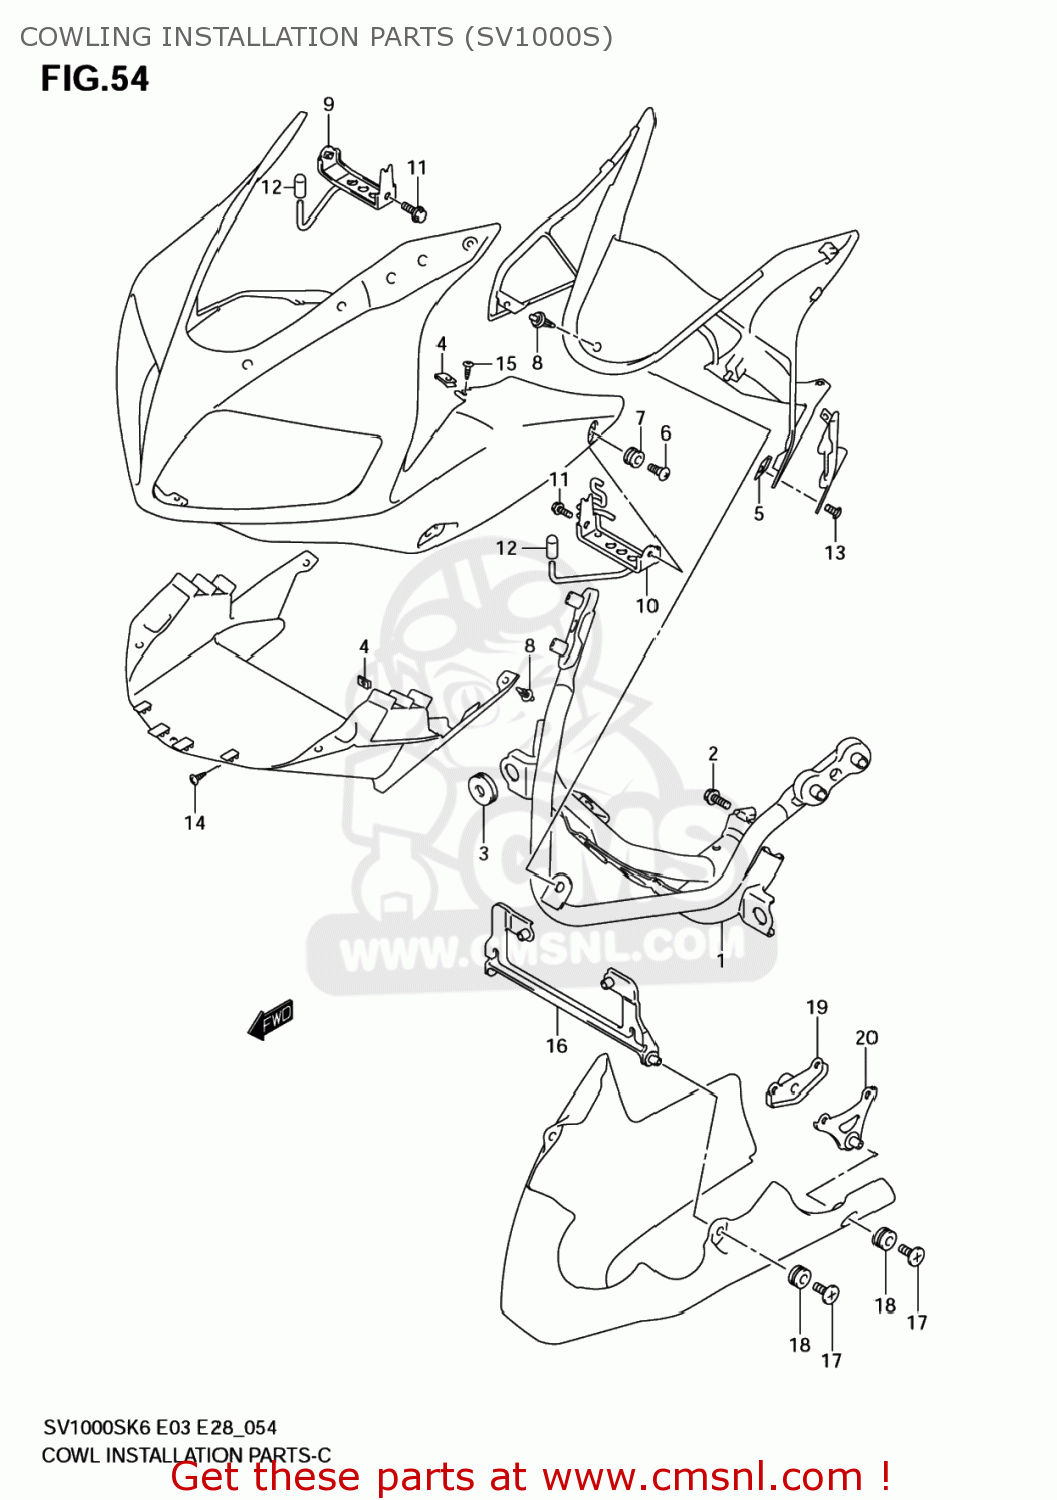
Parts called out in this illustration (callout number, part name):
1	BRACE,COWLING
2	BOLT
3	CUSHION
4	NUT,COWL
5	NUT
6	SCREW(6X20)
7	CUSHION
8	CLIP(BLACK)
9	BRACKET,COWLING FITTING,R
10	BRACKET,COWLING FITTING,L
11	BOLT
12	CAP
13	SCREW(5X16)
14	SCREW
15	SCREW(5X13)
16	BRACKET,UNDER COWLING FR
17	BOLT
18	CUSHION
19	BRACKET,UNDER COWLING,R
20	BRACKET,UNDER COWLING,L
